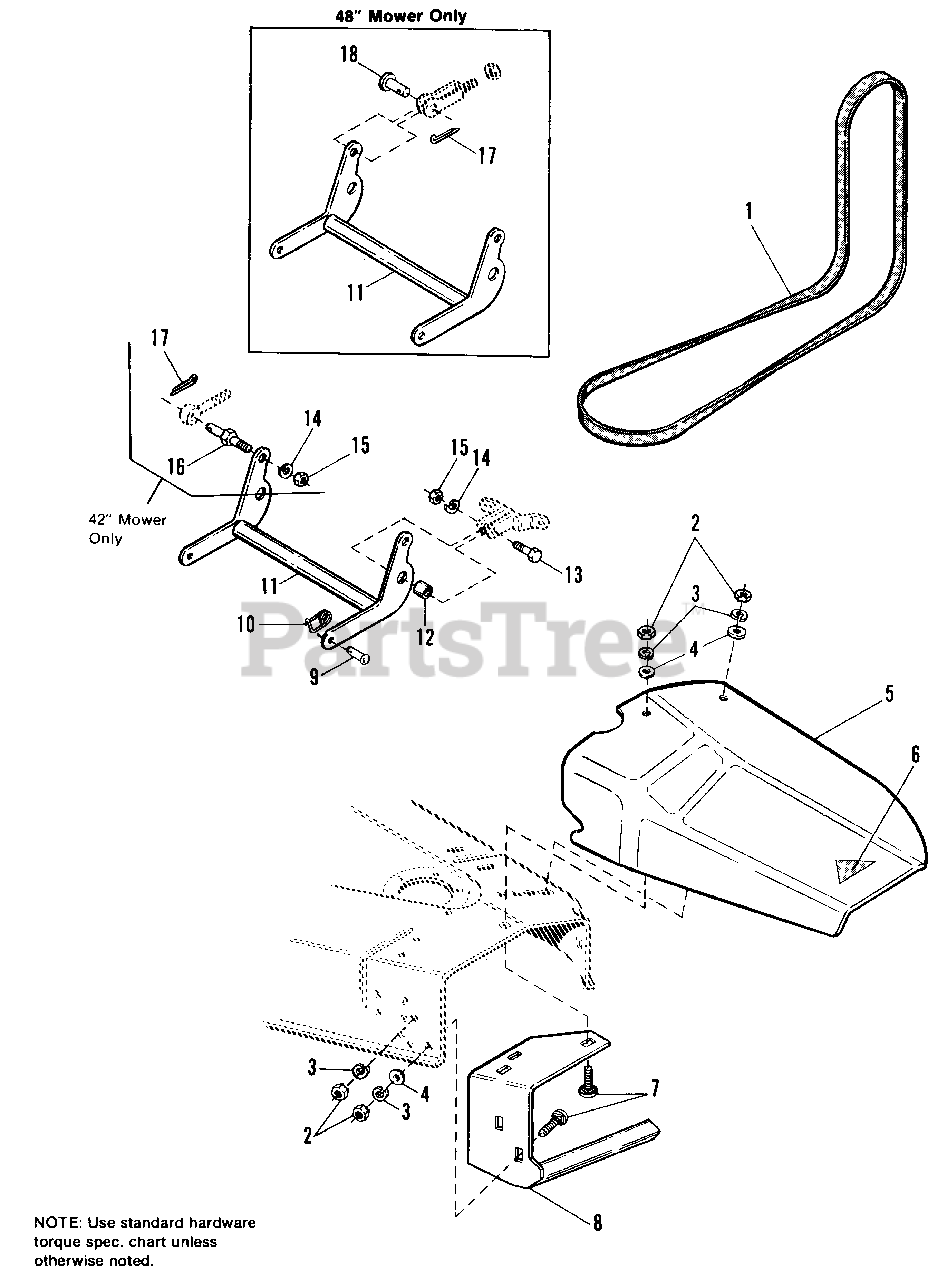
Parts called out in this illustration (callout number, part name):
1	V-BELT, PTO to Mower-42" Mower
1	V-BELT, PTO to Mower-48" Mower
2	NUT, Hex, 38-16
3	LOCKWASHER, 3/8
4	WASHER, Special
5	DEFLECTOR-42" Mower (Orange)
5	DEFLECTOR-42" Mower (Black)
5	DEFLECTOR-48" Mower (Orange)
5	DEFLECTOR-48" Mower (Black)
6	DECAL, OPEI
7	CARRIAGE BOLT, 3/8-16 x 1-1/4
8	GUARD ASSY., Stone-42" Mower
8	GUARD ASSY., Stone-48" Mower
10	PIN, Clip
11	ROCKER ARM ASSY.
13	CAPSCREW, Hex Hd., 1/2-13 x 1-1/4
14	LOCKWASHER, 1/2 (Qty. 2 on 48" Mower)
15	NUT, Hex, Jam, 1/2-13 (Qty. 2 on 48" Mower)
16	PIN, Pivot (42" Mower only)
17	COTTER PIN, 1/8 x 1
18	PIN, Yoke, (48" Mower only)
